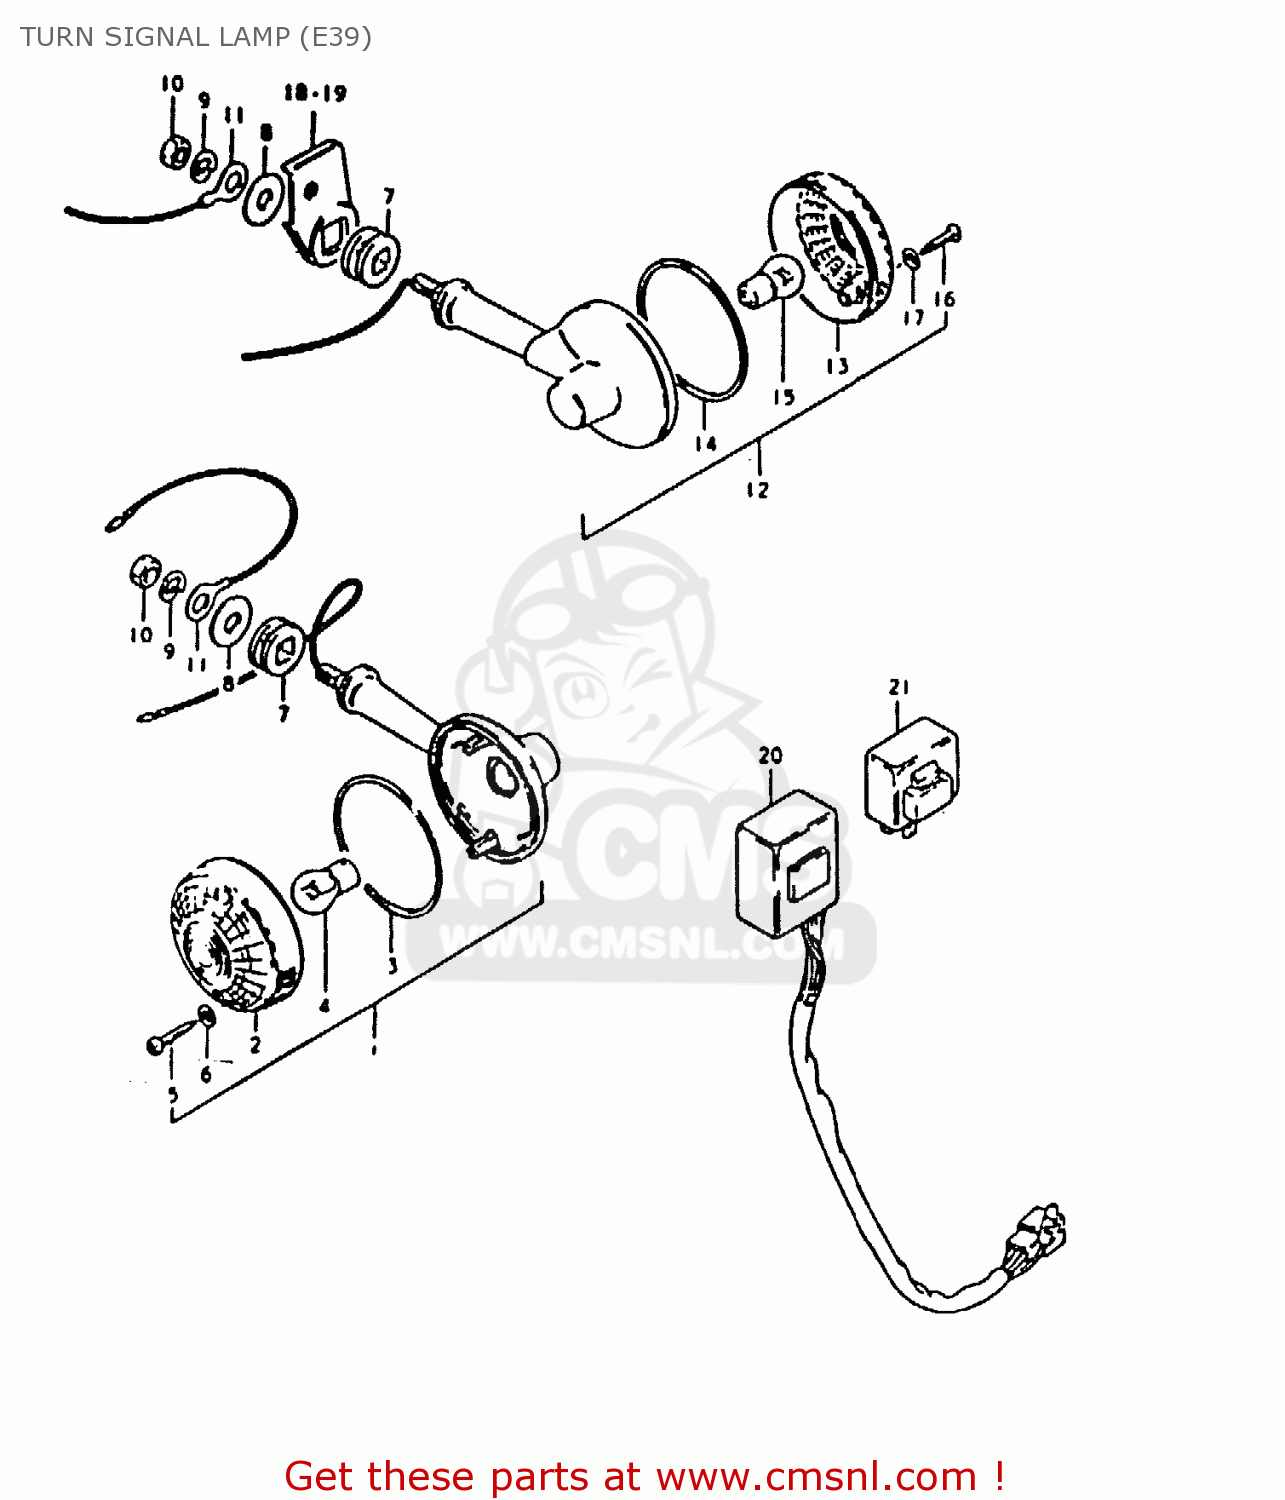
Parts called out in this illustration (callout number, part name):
1	LAMP, REAR TURN SIGNAL
2	LENS
3	GASKET (NAS)
4	SCREW (4X30)
5	GASKET (NAS)
6	BULB(12V21W)
7	CUSHION
8	WASHER (10.5X30X2.3)
9	LOCK WASHER
10	NUT
11	LEAD WIRE,EARTH
12	LAMP, REAR TURN SIGNAL
13	LENS
14	GASKET (NAS)
15	SCREW (4X30)
16	GASKET (NAS)
17	BULB(12V21W)
18	BRACKET,RR TURNSIGNAL LAMP,R
19	BRACKET,RR TURNSIGNAL LAMP,L
20	RELAY,TURN SIGNAL
21	UNIT,TURN SIGNAL CONTROL
